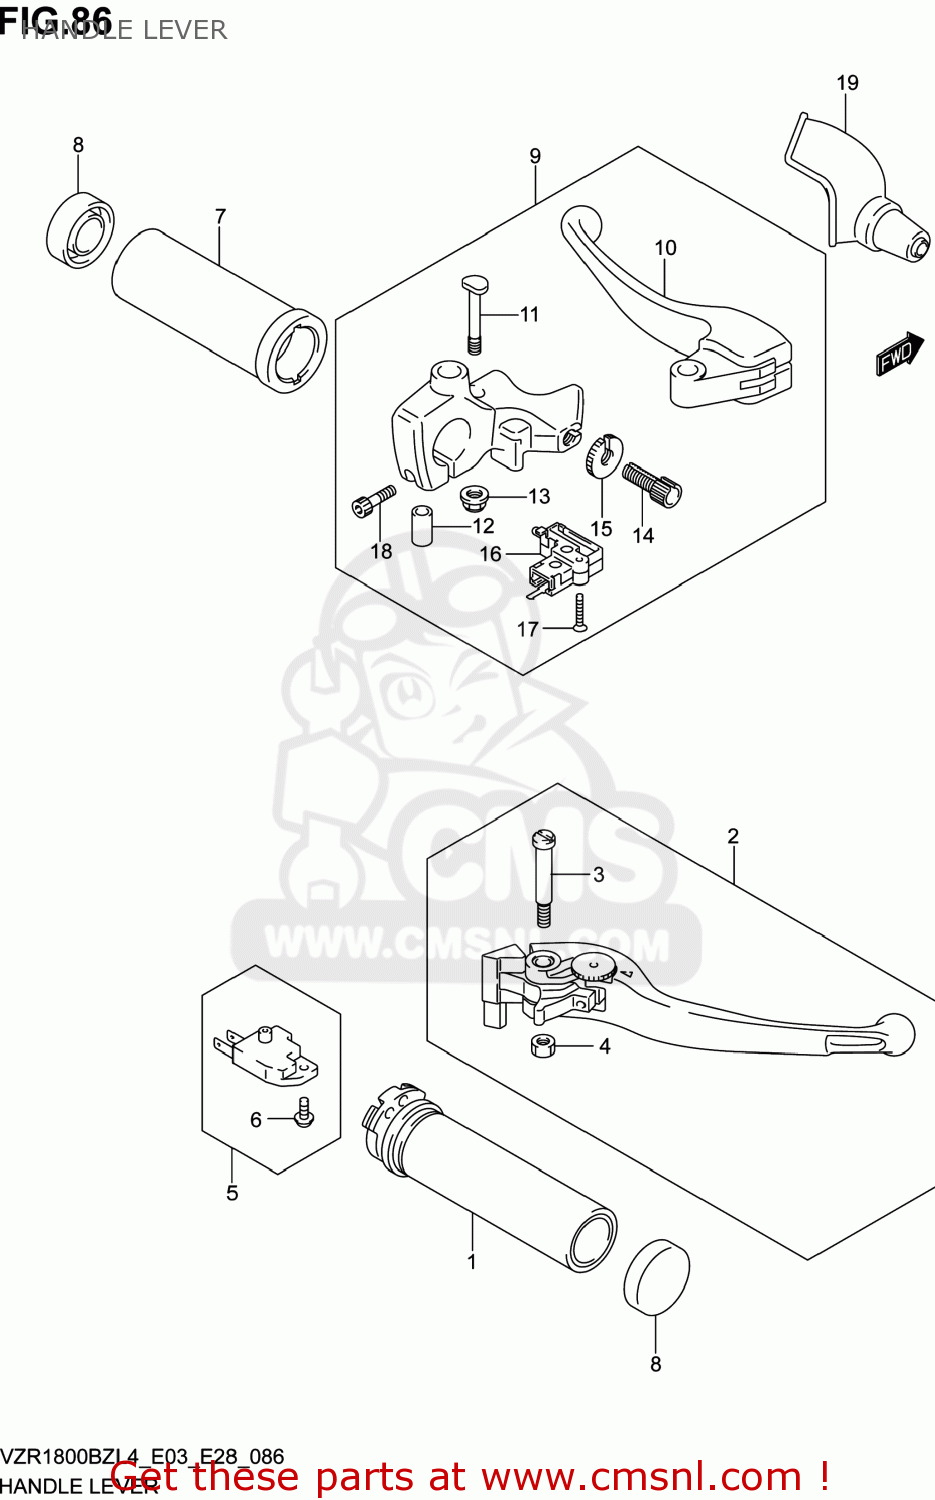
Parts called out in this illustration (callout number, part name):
1	GRIP,THROTTLE
2	LEVER ASSY,BRAKE
3	BOLT,PIVOT
4	NUT
5	SWITCH ASSY,FR BRAKE
6	SCREW
7	GRIP,L
8	CAP,GRIP,END
9	LEVER ASSY,CLUTCH
10	LEVER,CLUTCH
11	BOLT,LEVER PIVOT
12	COLLAR
13	NUT
14	ADJUSTER,WIRE
15	NUT,LOCK
16	SWITCH ASSY,CLUTCH
17	SCREW
18	BOLT
19	COVER,CLUTCH LEVER
